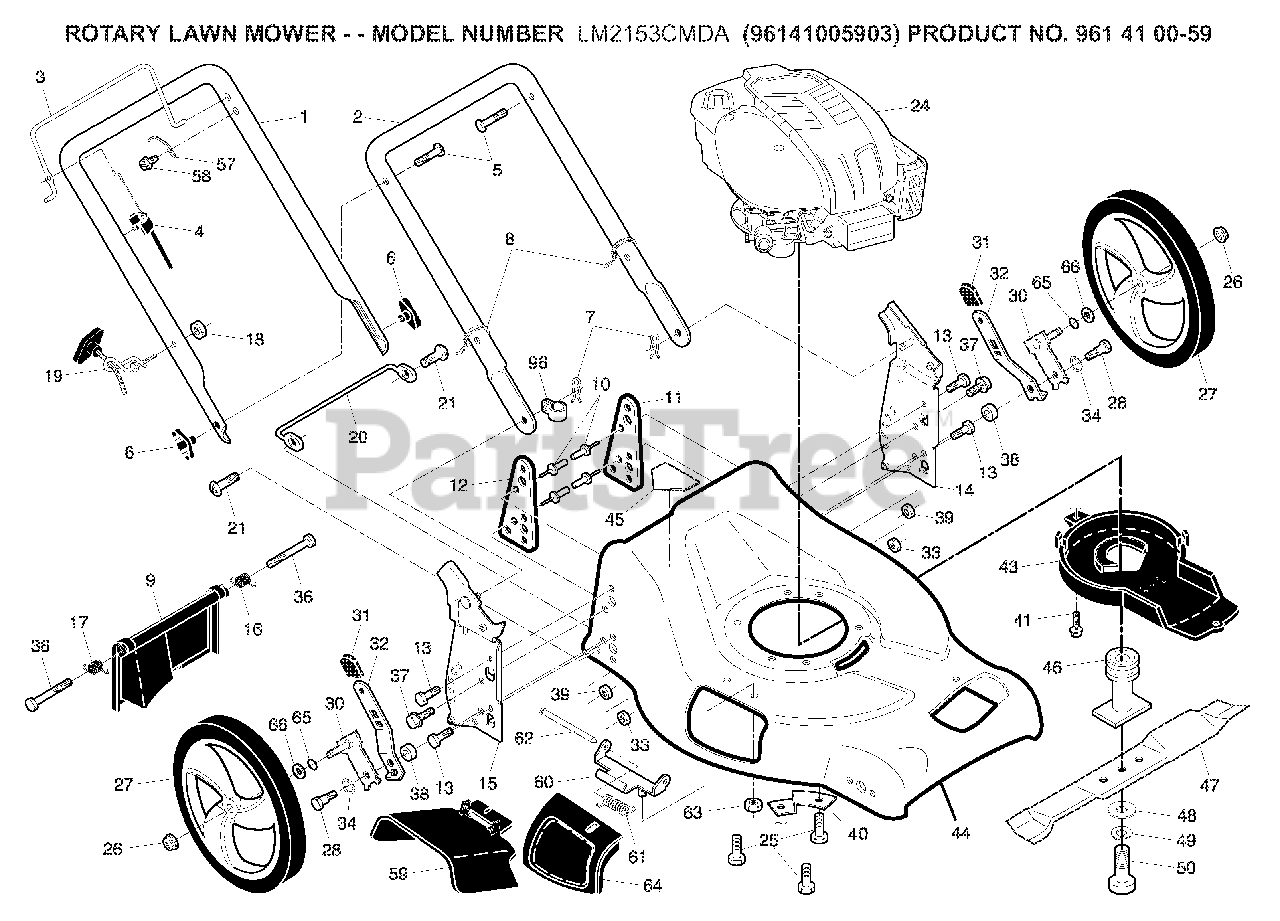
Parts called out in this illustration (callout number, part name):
1	HANDLE.UPER.D.ST.EZ
2	LOWER HANDLE
4	CABLE.MZR
5	BOLT, HANDLE 5/16-18X1.75
6	KNOB, DEFLECTOR
7	HAIRPIN COTTER
8	TIE GUIDE
9	REAR DOOR ASSY
10	RIVET BLIND
11	SUPPORT BRACKET LH
12	BRACKET.SUPRT.RH.21.FWGD
13	SCREW 14-20 X 5/8
14	BRKT.ASM.HNDL.21FGD.EZ
15	BRKT.ASM.HNDL.21FGD
16	SPRING.REAR.DOOR.EZ.21.LT
17	SPRING.REAR.DOOR.EZ.21.RT
18	NUT
19	GUIDE.ROPE.STD.BLK.ZIN
21	SCREW
25	BOLT 3/8-16X1-1/8
26	NUT.HEX.FLANGE.3/8-16.LOCKNUT
28	SHOULDER BOLT 5/16-18
30	ARM.ASM.AXLE.REAR.5/9.POS.BZP
31	SELECTOR KNOB
32	SELECTOR SPRING
33	NUT.71038.31-18.HEX.NYLOCK
34	WASHER FLAT
37	BOLT
38	SPACER.HEIGHT.ADJUSTER
39	NUT.FLANGE.5/16
40	BRACKET
41	SCREW.HEX.WSH
43	DEBRIS SHIELD
45	DECAL.INTERNATIONL.CUTFINGER
47	BLADE.21.PUSH
48	WASHER,HARDEN
49	LOCKWASHER
50	SCREW, HEX HD 3/8-24 X 1-3/8
57	BRACKET UPSTOP
59	DISCHARGE DEFLECTOR
60	HINGE BRACKET ASSEMBLY
61	SPRING.TORSION
62	ROD.HINGE.21
63	LOCKNUT
64	DOOR.MULCH.21.REAR
65	O-RING..070X.487.NEOPRENE
66	WASHER PM
96	CLIP.CABLE.BLK
